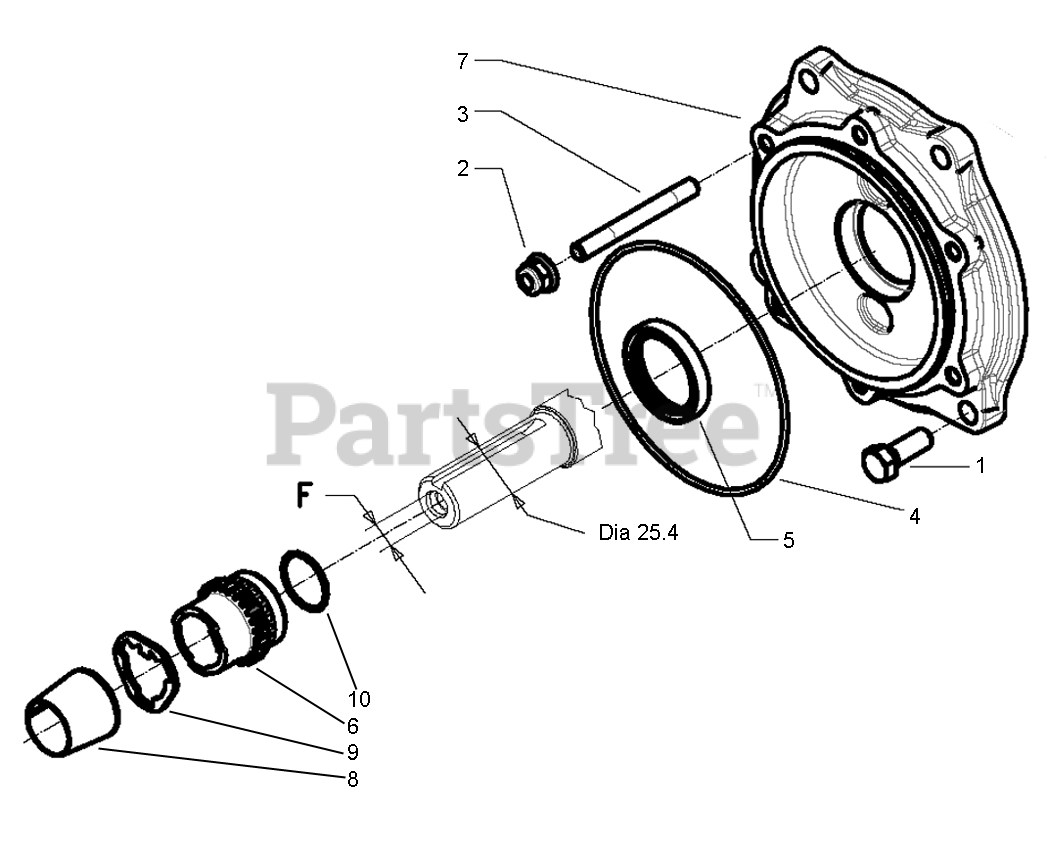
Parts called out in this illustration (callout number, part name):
1	SCREW TE 3/8X1"
2	SELFLOCK NUT M8 FLANG
3	STUD BOLT
4	O-RING
5	OIL SEAL
6	PUMP GEAR
7	ENGINE FLANGE GX390
8	CENTERING BUSHING
9	WASHER, SPACER
10	O-RING 2100 (25,12X1,78)
